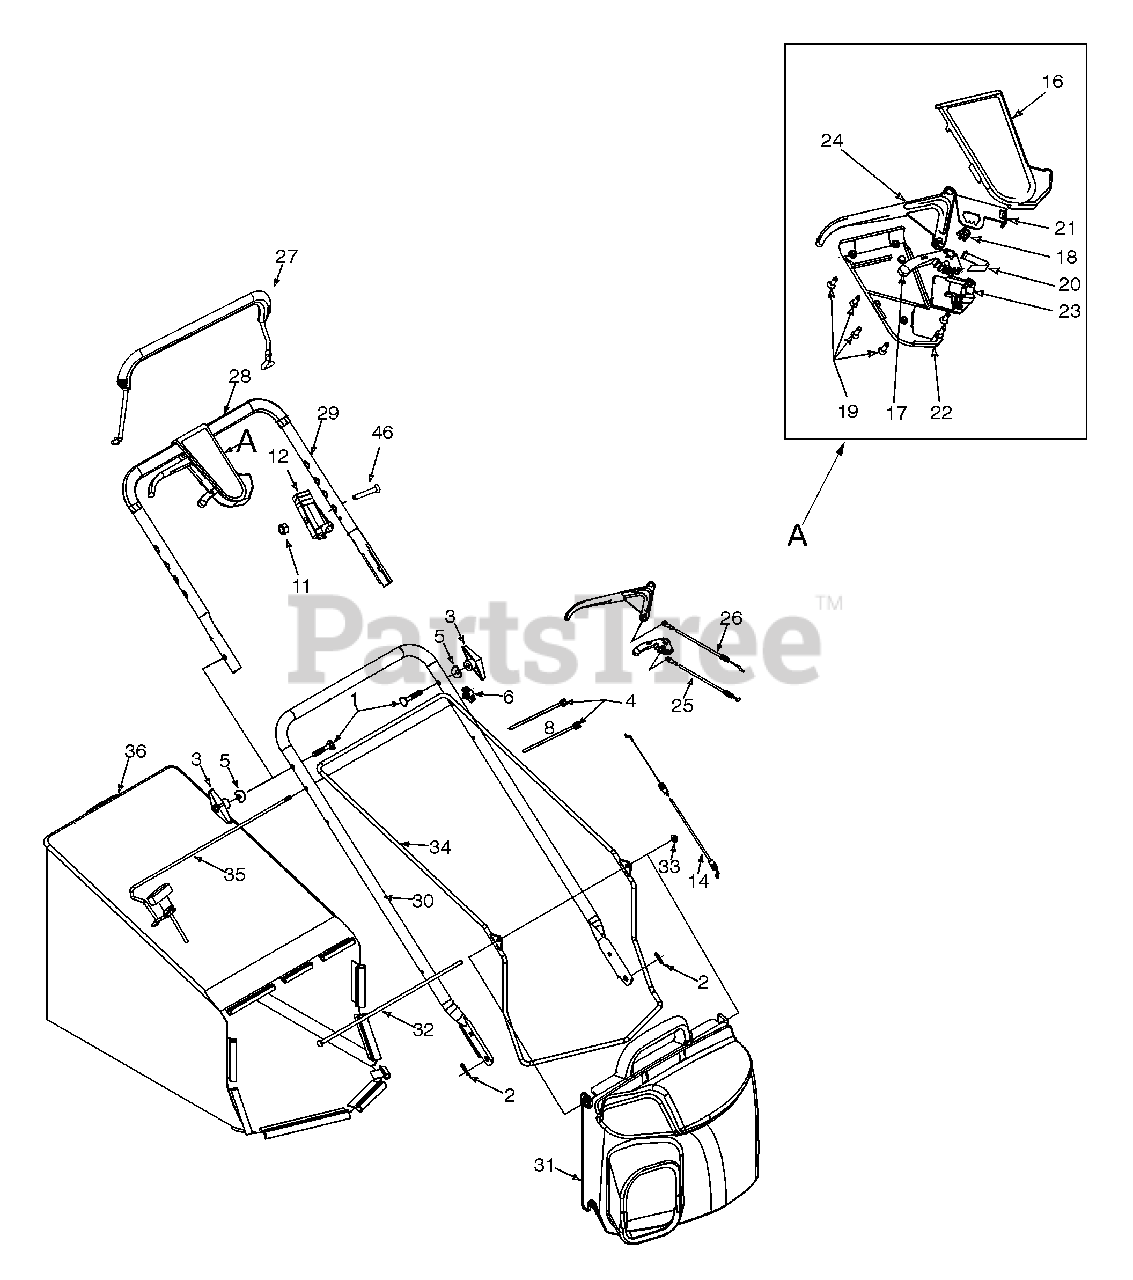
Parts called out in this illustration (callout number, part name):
1	Bolt Cur. Carr. 5/16-18 x 2.D
2	Cotter Pin .072 x 1.12 Lg.
3	Wingknob 5/16-18
4	Strap 4.3 Lg.
5	Wash. Sad. .320 ID x .830 OD
6	Handle Knob, 1/4-20
8	Screw 1/4-20 x 1.3
11	Nut 1/4-20 Top Locknut Insert
12	Housing, Control Cable
14	Control Cable 44" Lg.
16	Upper Control housing
17	6 Speed Shift Lever
18	Gear Insert
19	C Sunk Tap Screw #10-16 x .625
20	Shift Lever Spring
21	6 Spd. Rack Cable Brkt.
22	Lower Control Housing
23	Cable Mounting Cap
24	Control Lever
25	6 Spd. Cable
26	Self Prop. Cable 52"
27	Control Handle
28	Foam Grip
31	Grassbag Cover
